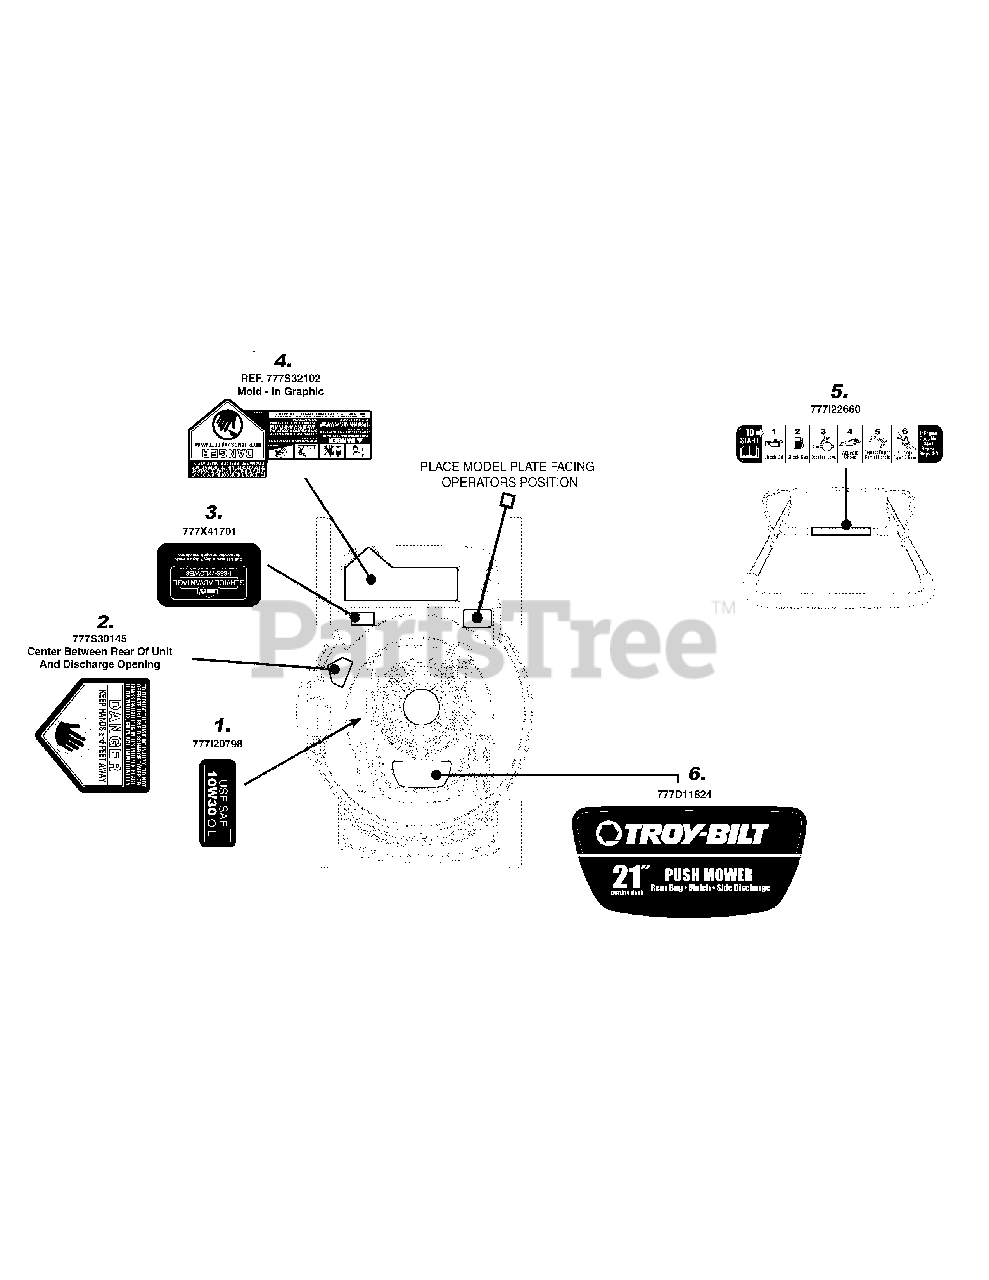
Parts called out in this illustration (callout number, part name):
1	LBL:MWR:SRHD:HONDA OIL CAPCTY
2	LABEL
3	LBL:LOWES SERVICE ADVANTAGE
5	LBL:MWR:HNDL:ST INSTR:HON ARCS
